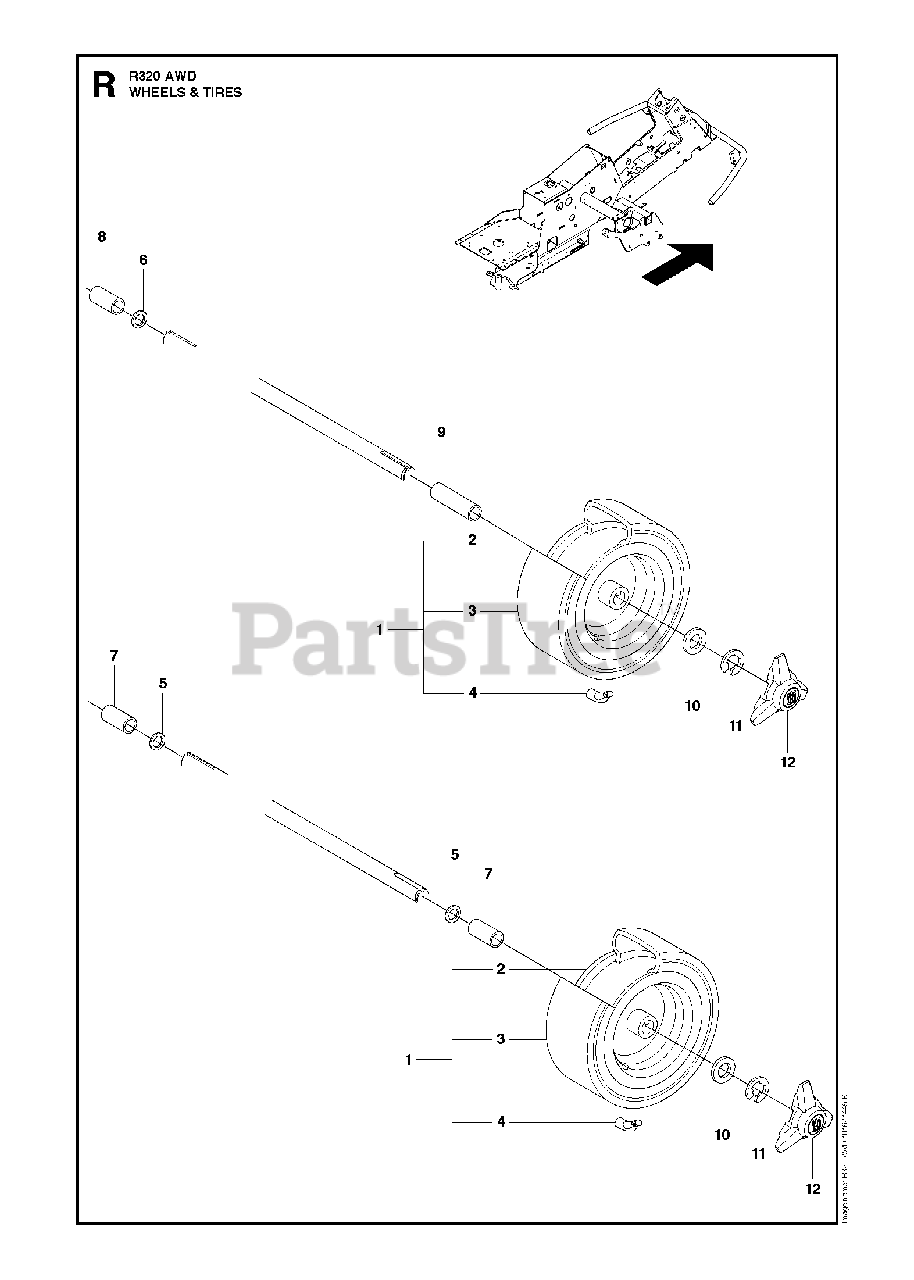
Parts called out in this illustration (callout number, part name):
2	RIM
3	TIRE
4	VALVE
7	SPACE SLEEVE
11	RETAINING RING
